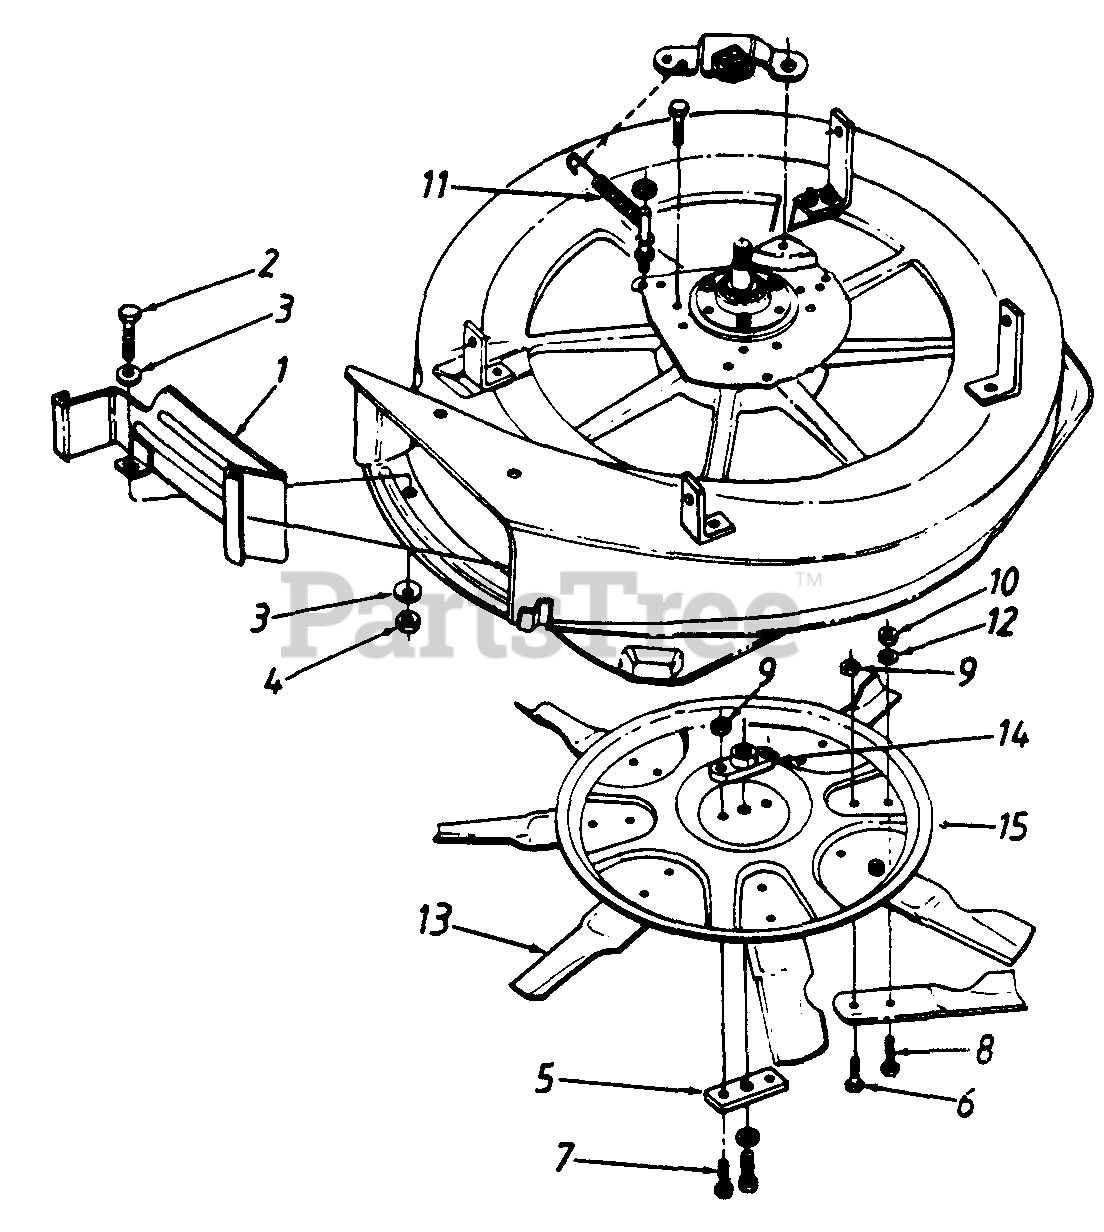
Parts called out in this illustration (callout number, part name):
1	Mulching Baffle Ass'y.
2	Hex Bolt 5/16-18 x .5"
3	Bell-Wash. .325" I.D.
4	Hex L-Nut 5/16-18 Thd.
7	Hex Bolt 5/16-24 x 1.25" Lg.(Gr. 5)
8	Hex Bolt 3/8-24 x .88" Lg.
9	Hex L-Nut 5/16-24 Thd
10	Hex L-Nut 3/8-24 Thd. (Gr. 5)
11	Extension Spring 3.2" Lg.
12	Fl-Wash. .406" I.D. x .75"
13	30" Mulching Blade Tip
14	Blade Adapter
15	30" Mulching Blade Disc
